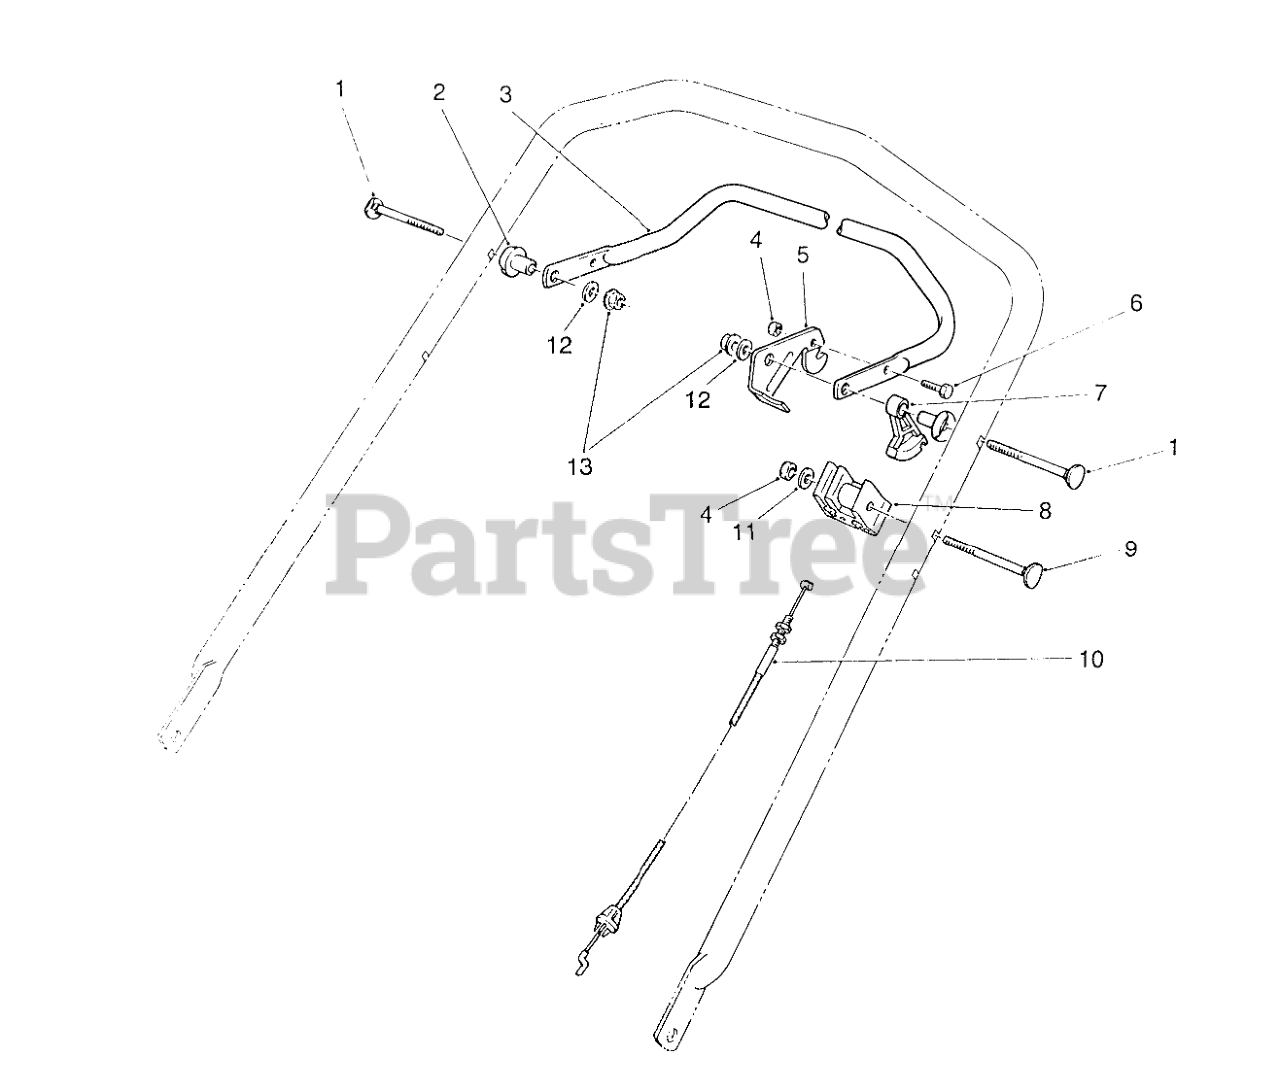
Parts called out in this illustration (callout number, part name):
1	SCREW-HANDLE
2	SPACER-SUPPORT
3	Bar-Control
4	NUT-LOCK, NI
5	CONTROL LEVER
6	SCREW-HH
7	LEVER-TRACTION
8	SUPPORT-CABLE
9	SCREW-HANDLE
10	TRACTION CABLE
11	WASHER-FLAT
12	WASHER-PLAIN
13	NUT-LOCK, NI
